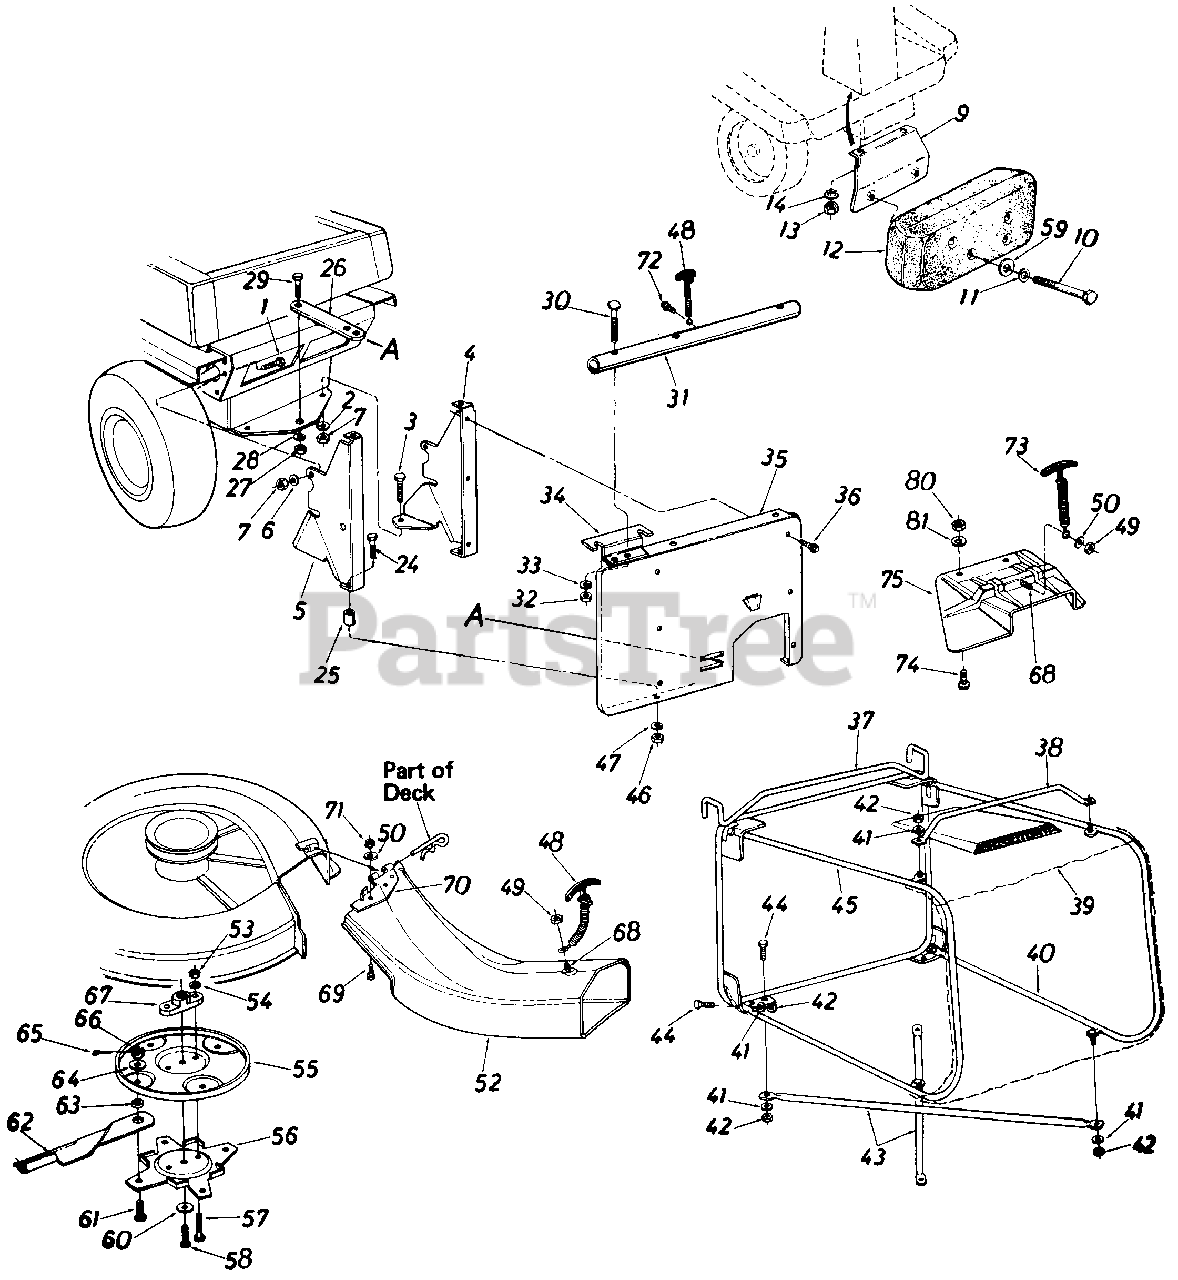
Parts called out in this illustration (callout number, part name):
1	Hex Bolt 5/16-18 x 1.0" Lg.*
2	L.-Wash. 5/16" I.D.*
3	Hex Bolt 5/16-18 x 1.0" Lg.*
4	Catcher Support Brkt-R.H.
5	Catcher Support Brkt-L.H.
6	L.-Wash. 5/16" I.D.*
7	Hex Nut 5/16-18 Thd.*
9	Counterweight Support Brkt. Ass'y
10	Hex Bolt 3/8-16 x 4.5" Lg.*
11	Belleville Wash. .40" I.D. x .88" O.D.
12	Counterweight 38 Ibs.
13	Hex Nut 5/16-18 Thd.*
14	L.-Wash. 5/16" I.D.*
24	Hex Bolt 5/16-18 x 1.50" Lg.*
25	Spacer .380" I.D. x .47" O.D. x 1.0" Lg.
28	L.-Wash. 1/2" I.D.*
29	Hex Bolt 1/2-20 x 1.0" Lg.*
30	Curved Carriage Bolt 5/16-18 x 1.75" Lg.
33	L.-Wash. 5/16" I.D.*
34	Grass Catcher Support Plate
35	Rear Discharge Panel
36	Hex Wash. Hd. Self Tap. Scr. 1/4- 0 20 x .50" Lg.
37	Grass Catcher Frame Ass'y.
42	Hex L.-Nut 1/2-20 Thd
43	Bottom Cross Brace
44	Hex Bolt 1/4-20 x .62" Lg.*
47	L-Wash. 5/16" I.D.
48	Hook Latch Ass'y.
49	Hex L.-Nut 1/4-20 Thd.
50	Fl.-Wash. 1/4" I.D.*
52	R.D. Banana Chute Ass'y.
53	Hex Nut 5/16-24 Thd.*
54	L.-Wash. 5/16" I.D.*
55	Upper Blade Disc
58	Hex Bolt 3/8-24 x 1.0" Lg.
59	Fl.-Wash. .39" I.D. x 1.12" O.D.
60	Bell.-Wash. 39" I.D. x 1.38"
61	Shld. Bolt. .50" Dia. x .360 0 Spec.
62	30" Blade Tip
63	Spacer .505" I.D. x .75" O.D. x 1.25" Lg.
64	Fl.-Wash. .50" I.D. x 1.25" O.D.
65	Cotter Pin 3/32" Dia. x 1.0" Lg.*
66	Hex Slotted Nut 1/2-20 Thd.
67	Blade Adapter
68	Hex Bolt 1/4-20 x .50" Lg.*
69	Truss Mach. Scr. 1/4-20 x .50" Lg. *
72	Hex AB Tap Scr. 1/4 x .62" Lg.
73	Hook Latch Ass'y. 7" Lg.
74	Truss Mach. Scr. 1/4-20 x 50" Lg. *
75	R D Chute Extension
80	Hex L.-Nut 1/4-20 Thd.
81	Fl.-Wash. .281" I.D. x .50" O.D. x .063
